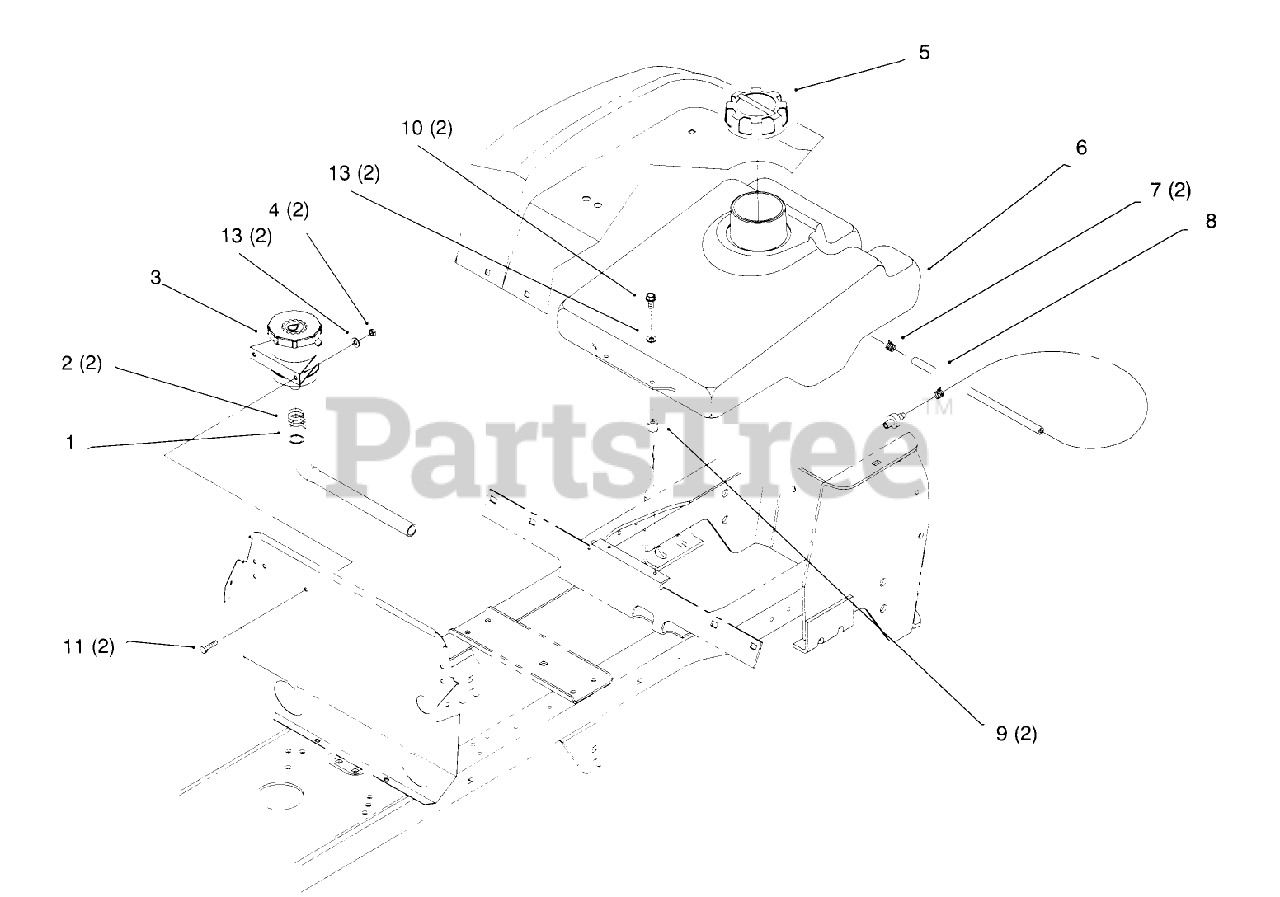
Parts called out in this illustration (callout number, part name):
1	HOSE - HYDRO
2	CLAMP-HOSE
4	NUT-LOCK, NI
5	GAS CAP ASM
7	CLAMP-HOSE
8	HOSE-FUEL
9	SPACER - FUEL TANK
10	SCREW-HH
10	SCREW-HWH
11	SCREW-HH
13	WASHER-FLAT
